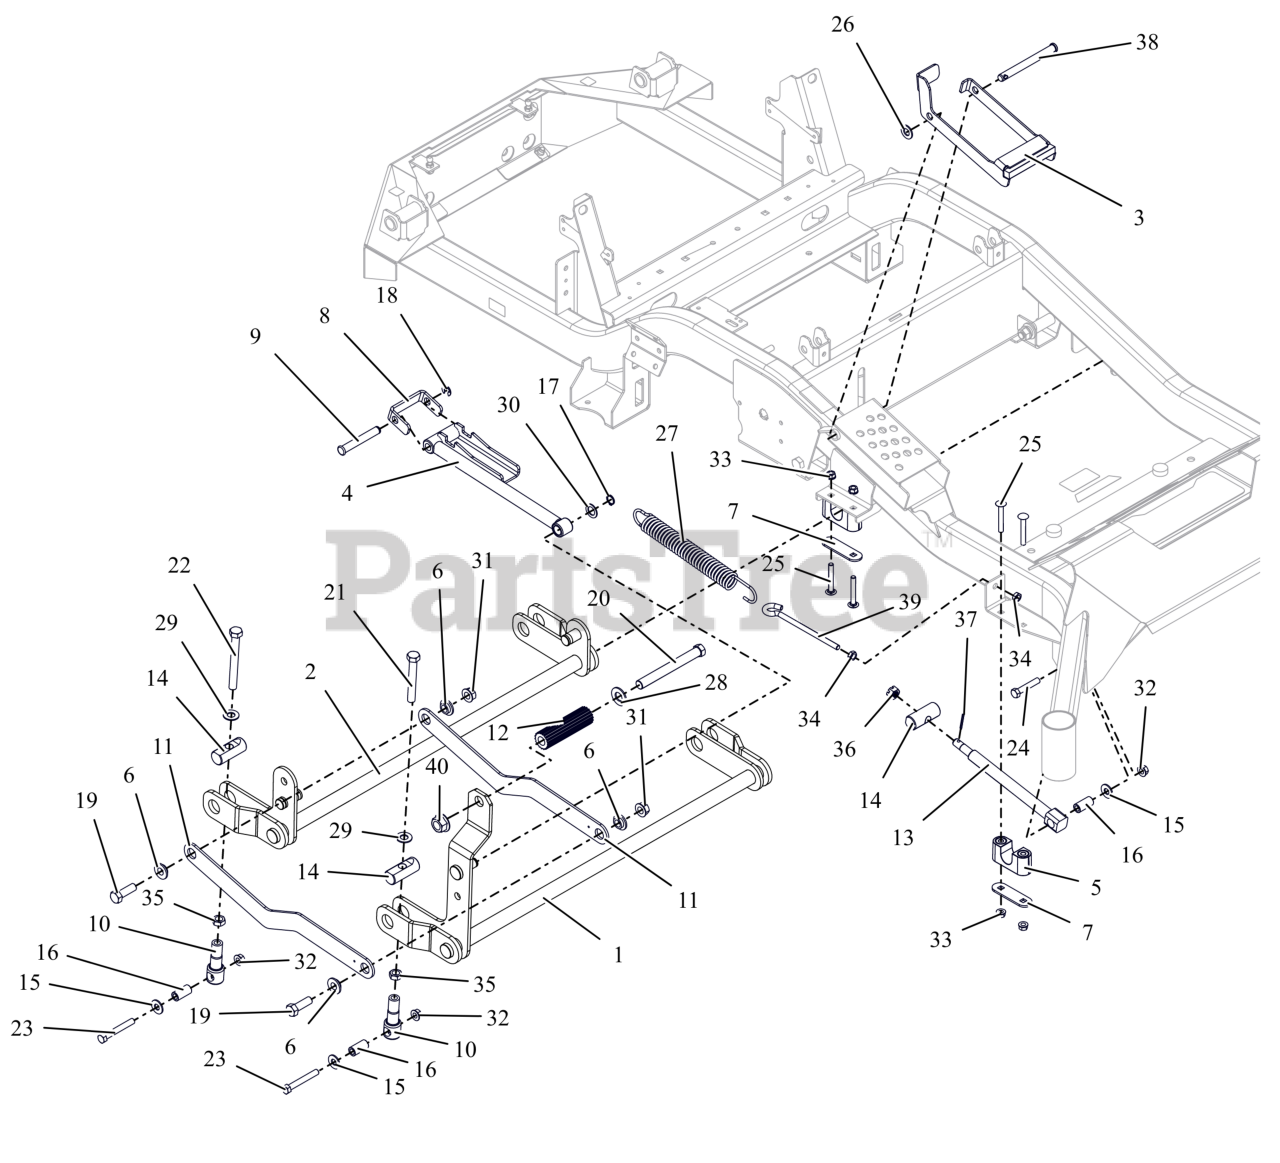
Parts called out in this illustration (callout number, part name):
1	WLDMT, FRONT DECK LIFT PIVOT
2	WLDMT, REAR DECK LIFT PIVOT
3	BRKT, HOC TRANSFER LOCK
4	WLDMT- HOC ARM
5	ASM-BUSHING, DECK LIFT
6	BSHG-FLG .515X.750X.395X1.120
7	PLATE, BEARING SUPPORT
8	BRKT, HOC LINE
9	PIN, .499/.494 x 3.385 CLEVIS
10	LINK, DECK LIFT FORMED
11	LINK- DECK LIFT
12	ROD, FOOT PEDAL (BLACK)
13	DRAG,LINK-HD
14	PIN, DECK LIFT
15	WSHR,FLT .438X1.00X.083 ZCC
16	SPACER, DECK LEVELING
17	RG-RTNG-EXT .625X.050
18	RG-RTNG-EXT .500X.042 (E)
19	BLT,HEX .50-13X1.50 G5 ZCC
20	BLT, HEX .62-11X5.50 G5 FBP
21	BLT, HEX .50-13X3.50F G5 ZCC
22	BLT, HEX .50-13X4.50F G8 ZCC
23	BLT, HEX .38-16X2.75 G8 ZCC
24	BLT,HEX .38-16X2.00 G5 ZCC
25	BLT, RHSSN.31-18X2.25 G5 ZCC
26	WSHR-FL-NYL .518X1.000X.080
27	SG-TENS .162X1.25X8.25 E-COAT
28	WSHRFLT 5/8SAE CARBHARD FBP
29	WSHR, FLT .557X1.040X.102 ZCC
30	WSHR, FLT .630X1.005X.062 ZCC
31	NUT-LK-TOP-FLG .500-13 GF ZCC
32	NUT-LK-TOP-FLG .38-16 ZC120
33	NUT,LK-CTR-FLG .31-18 GF ZCC
34	NUT-JAM .375-16 GR2 E-COAT
35	NUT-JAM .500-13 G2 ZCC
36	NUT-SL .50-13
37	PIN,CTR.12X1.25EXTPRSQCT ZC120
38	PIN-SLIC .50X4.97X4.55 -ZCC
39	BOLT, J-HOOK .38-16X5.25 E-COAT
40	NUT,FLG-TOP LK .625-11 FBP
